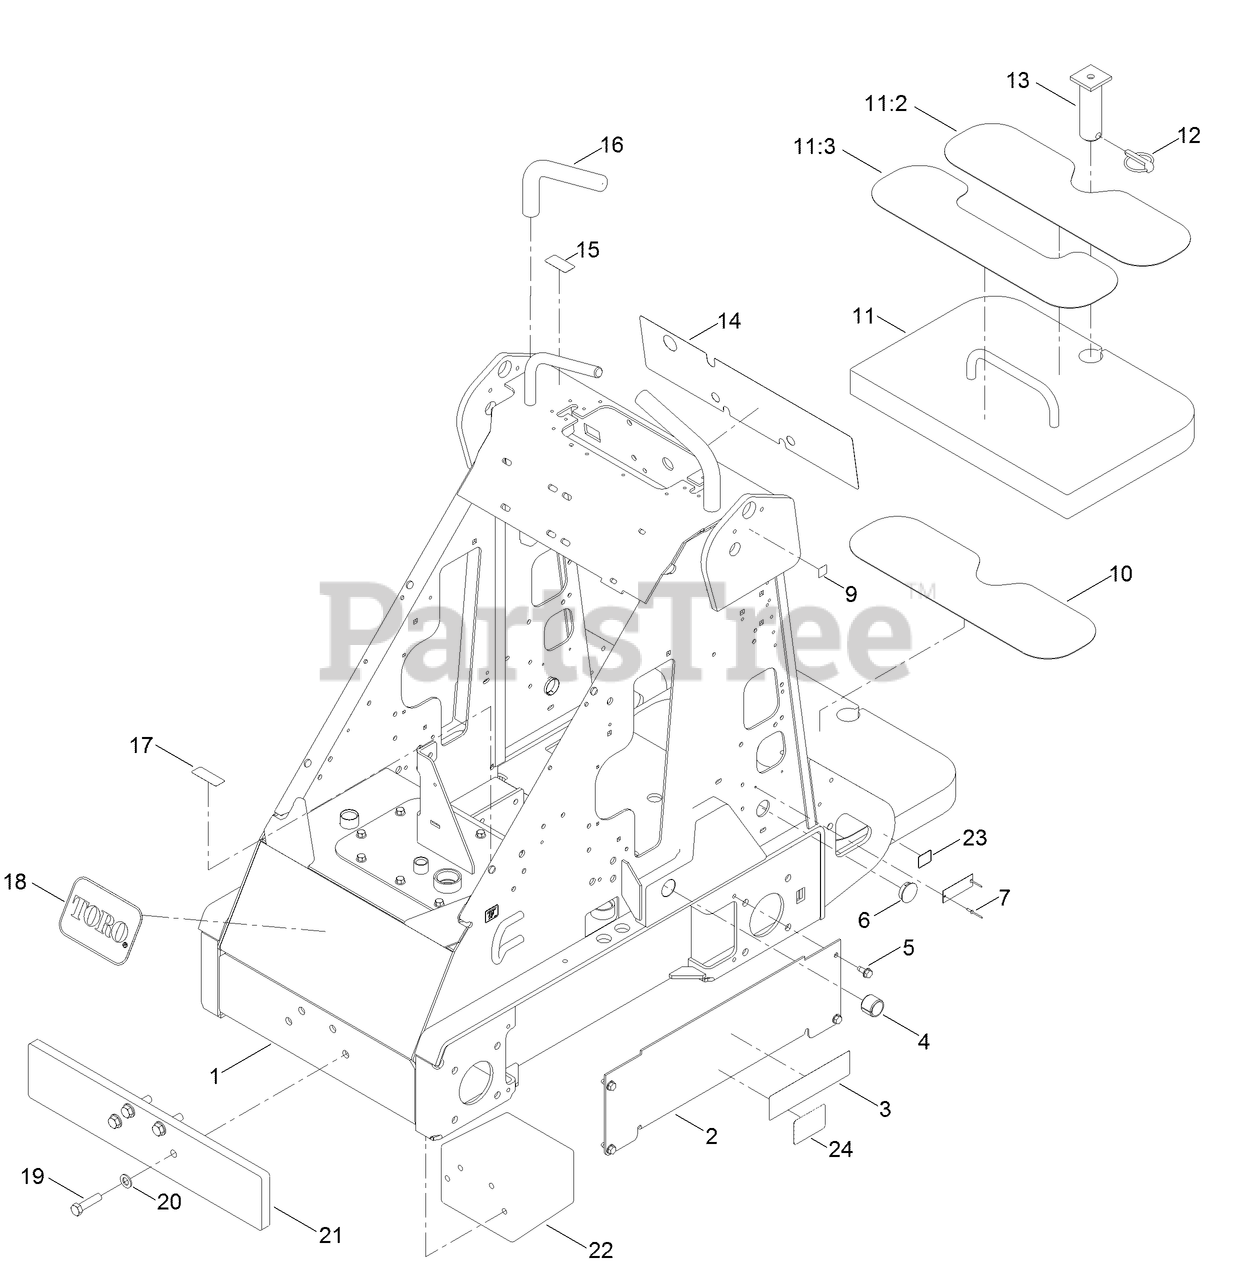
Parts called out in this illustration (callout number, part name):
1	FRAME ASM
2	COVER-HOSE
4	BUSHING-TENSION
5	SCREW-HWHTF
6	PLUG-HOLE
7	RIVET
9	DECAL-POINT, LIFT
10	TREAD-FOOT
11	COUNTERWEIGHT ASM
11:2	TREAD-FOOT
12	PIN-LYNCH
14	DECAL-CONTROL PANEL
15	DECAL-PROTECTION, EAR
16	GRIP-CUSHION
17	DECAL-OIL, HYD
18	DECAL
20	WASHER
21	WEIGHT-COUNTER
22	WEIGHT-FRONT, COUNTER
23	DECAL-TIEDOWN
24	DECAL-WATER LEVEL
